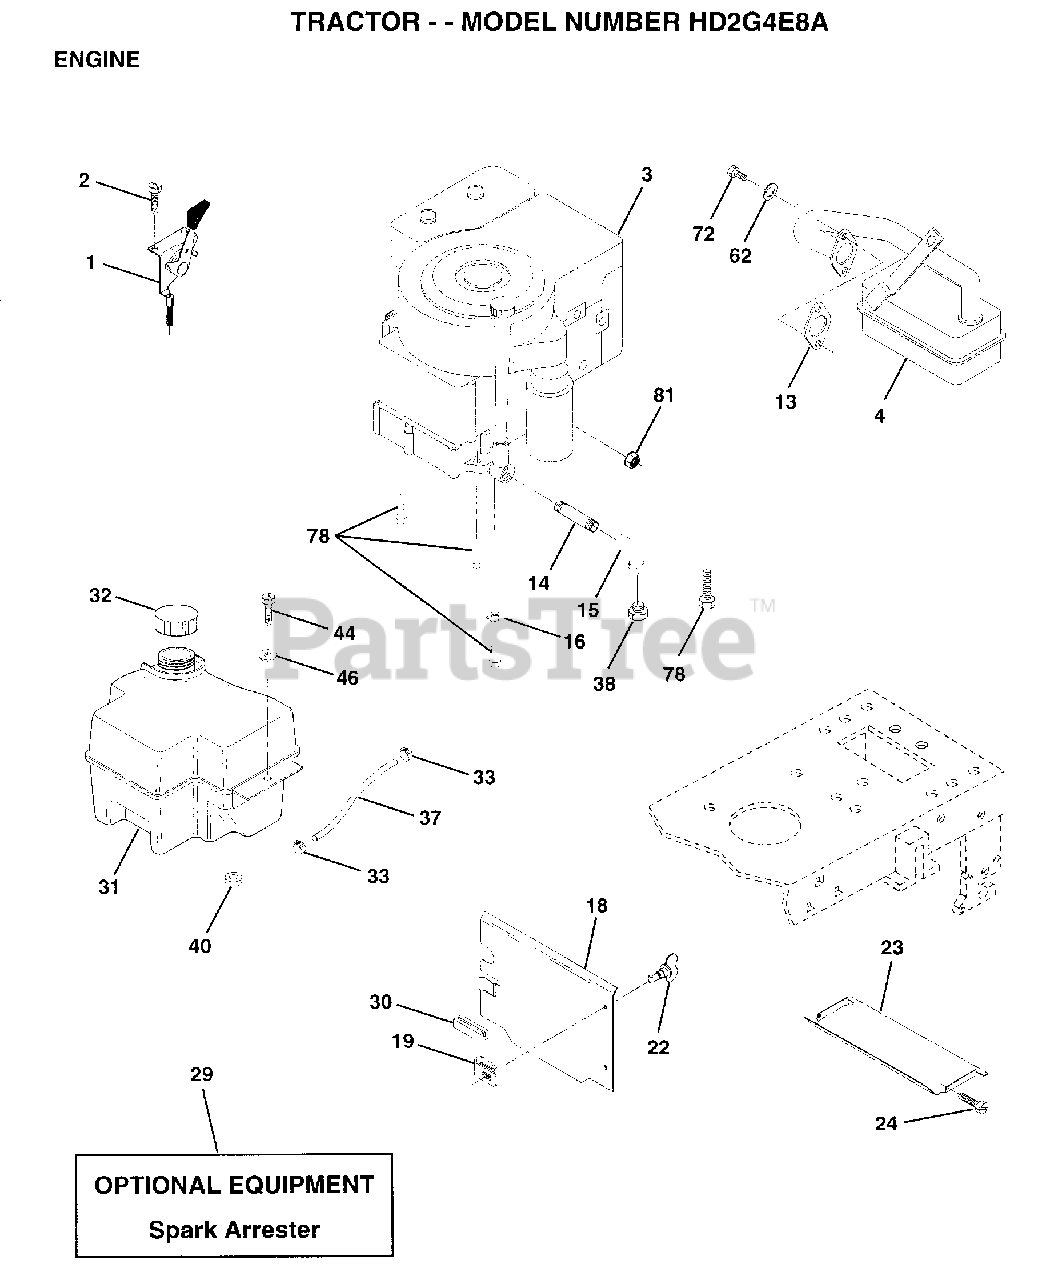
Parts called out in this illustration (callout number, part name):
1	CONTROL THROTTLE
2	SCREW LT
4	MUFFLER
13	GASKET ENG 1 313 LD TIN PLATED
14	PIPE NIPPLE
15	ELBOW
16	LOCKWASHER
18	SHIELD HEAT
19	RECEPTACLE LT
22	MANUAL.OWN.2032B5
23	HEAT SHIELD
24	SCREW
32	CAP ASM FUEL
33	HOSE CLAMP
37	LINE FUEL
44	SCREW HEX CRT
46	WASHER
62	LOCKWASHER
72	SCREW
78	SCREW
81	NUT
